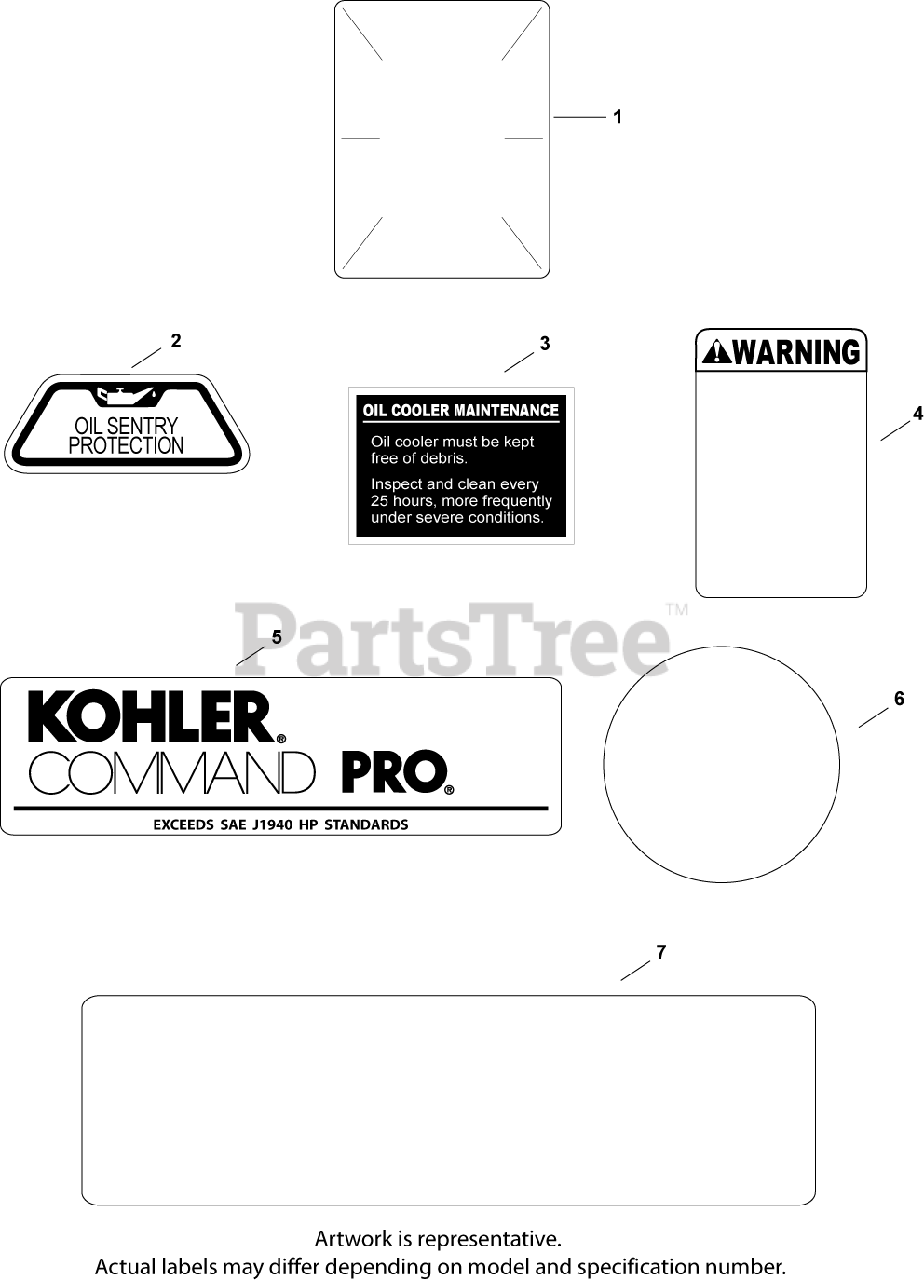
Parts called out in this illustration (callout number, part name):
1	DECAL, CLEAR LAMINATE USE 25 113 70-S
2	DECAL, OIL SENTRY - (#DSC)
3	DECAL, OIL COOLER - (#DSC)
4	DECAL, 17 HP - DISC.
5	DECAL, 23 HP - DISCONTINUED
6	DECAL, GRASS SCREEN
7	DECAL, COMMAND (GASEOUS) - DISCONTINUED
